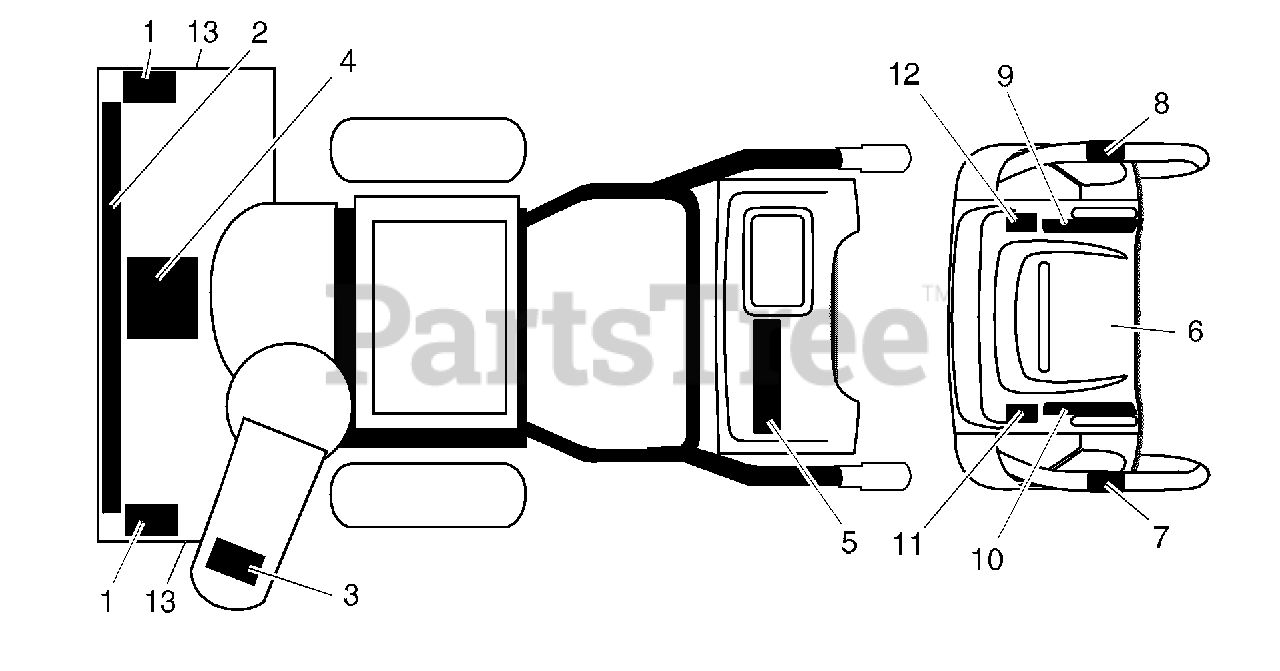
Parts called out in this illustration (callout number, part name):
1	Decal, Danger
2	Decal, Husqvarna
3	Decal, Danger, Deflector
4	Decal, Danger
5	Decal, Husqvarna, 1130SBE
6	Decal, Instruction
7	Decal, Traction Lever
8	Decal, Auger Lever
9	Decal, Speed Control
10	Decal, Remote Deflector
11	Decal, LH Trigger
12	Decal, RH Trigger
13	Decal, Husqvarna, Crown
13	Owner’s Manual, English
13	Owner's Manual, French
